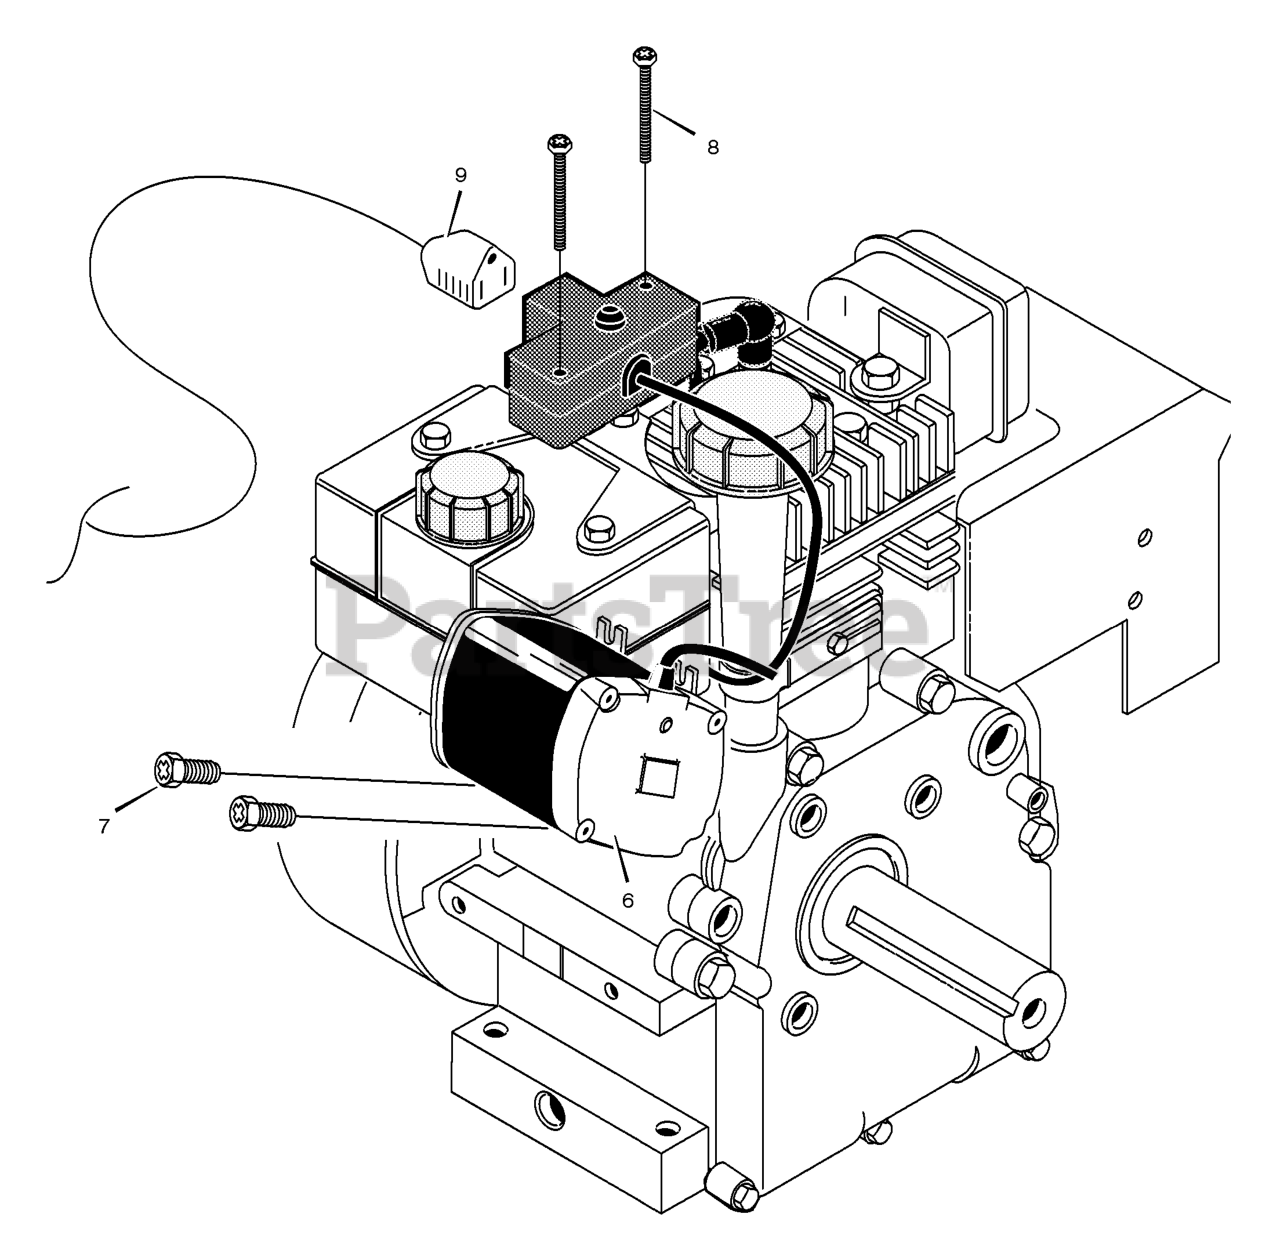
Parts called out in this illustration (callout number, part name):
6	MOTOR, STARTER
8	SCREW
9	CORD, Electric, 10FT. 110V
